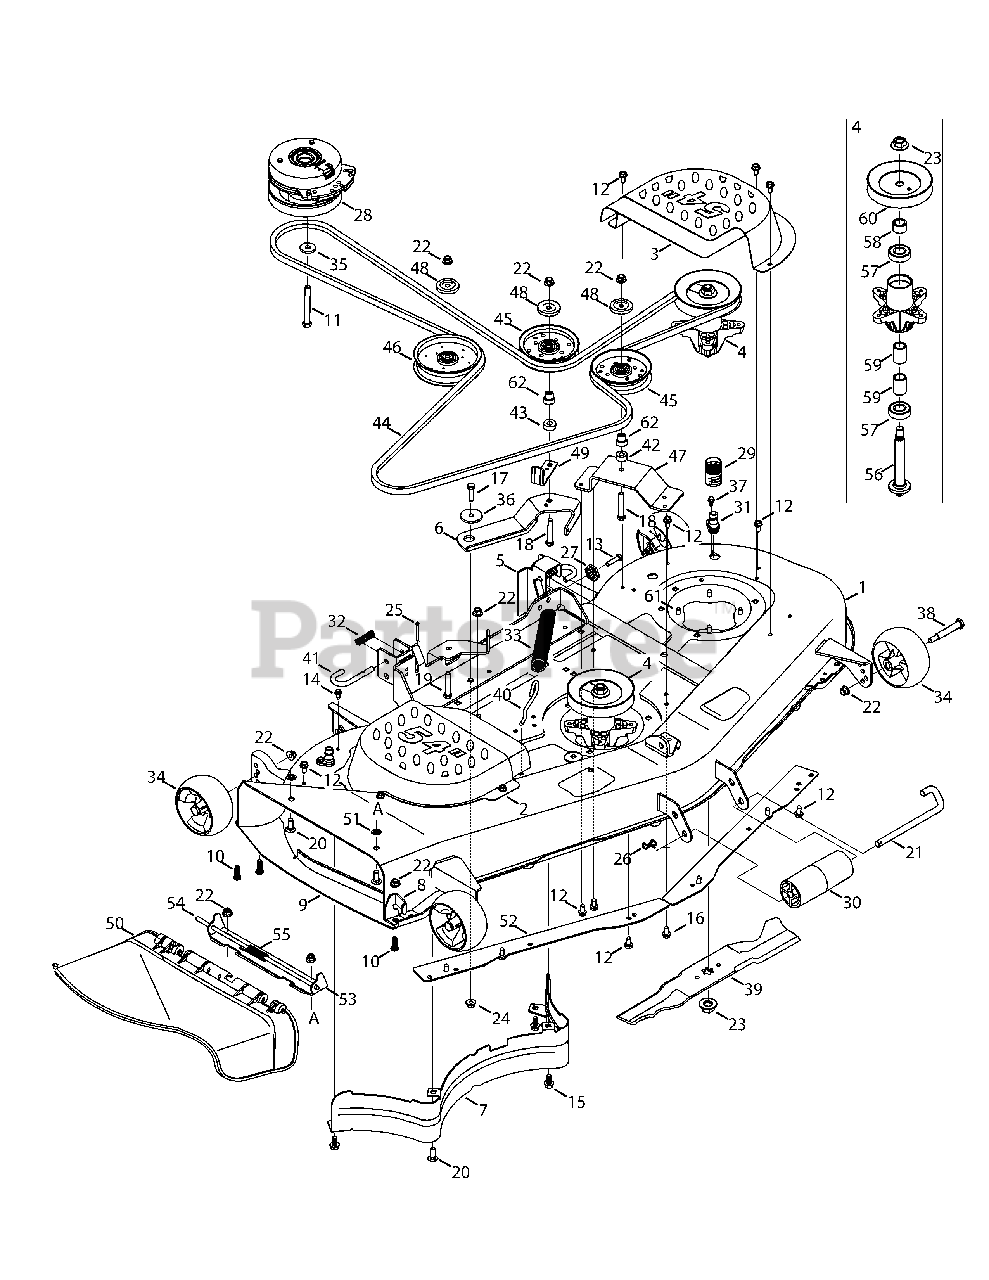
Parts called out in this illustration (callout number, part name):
2	Belt Cover, RH
3	Belt Cover, LH
4	Spindle Assembly
5	Deck Lift Bracket
6	Idler Arm
10	Hex Cap Screw, 3/8-16, 1.00
11	Hex Cap Screw, 7/16-20 x 3.50
12	Hex Washer Screw, 5/16-18 x .750
13	Hex Cap Screw, 5/16-18 x 1.25
14	Hex Washer Screw, 1/4-20 x .500
15	Hex Washer Screw, 3/8-16 x .75
16	Self Tapping Screw, 5/16-18 x .875
17	Hex Cap Screw, 3/8-16 x 1.25
18	Hex Cap Screw, 3/8-16, 2.25
19	Hex Cap Screw, 3/8-16 x 2.00
20	Carriage Screw, 3/8-16 x 1.00
21	Roller Pin, 1/2" x 7.31 Lg
22	Flange Lock Nut, 3/8-16
23	Hex Flange Nut, 5/8-18
24	Flange Lock Nut, 3/8-16
25	Cotter Pin, 5/32 x 1.25
26	Bow-Tie Cotter Pin
27	Deck Adjustment Gear
28	Electric PTO Clutch
29	Water Nozzle Adapter
30	Front Roller
31	Deck Wash Nozzle
32	Compression Spring, .66 x 1.9
33	Extension Spring, 1.25 OD x 1.751
34	Deck Ball Wheel, 5.0
35	Flat Washer, .450 x 1.25 x .164
36	Shoulder Spacer, .884 x .190
37	Shoulder Screw, .500 x 1/4-20
38	Shoulder Screw, .5 x 2.5 x 3/8-16
39	Blade, 18.5
40	Deck Spring Rod
41	Deck Hanger Rod
42	Spacer, .385 ID x .875 OD x .458
43	Spacer, .406 ID x 1.00 OD x .380
44	V-Belt
45	Idler Pulley, 4.25 Dia
46	Idler Pulley, 5.00 Dia.
47	Bracket, Idler, Stationary
48	Pulley Cap
49	Belt Guard Bracket
50	Discharge Chute Assembly
51	Push Nut, 3/8
53	Chute Bracket
55	Torsion Spring
56	Spindle Shaft, 6.11 Long
57	Ball Bearing
58	Spacer, .82 x 1.15 x .69
59	Spacer, .792 x 1.06 x 1.52
60	V-Type Pulley, 5.39
61	Hex Washer Screw, 5/16-18 x .750
62	Shoulder Spacer
